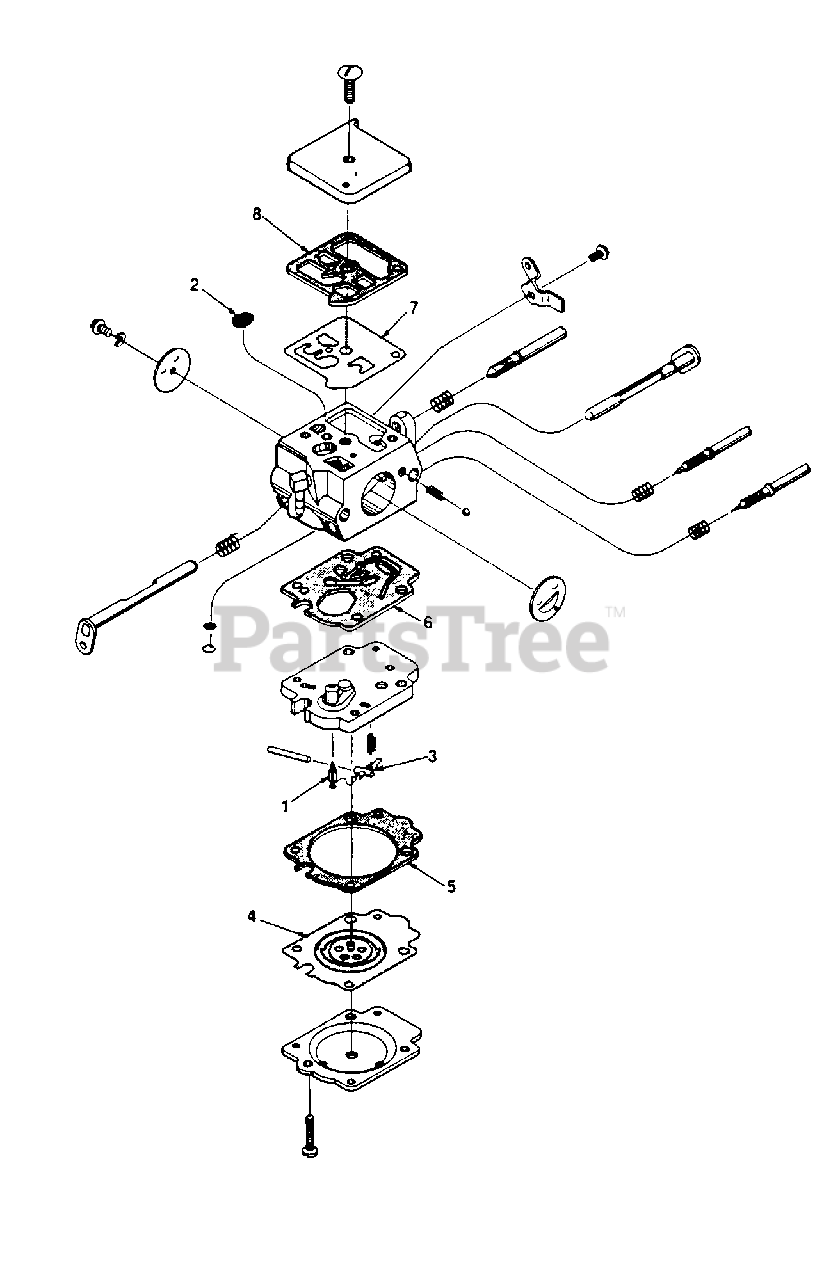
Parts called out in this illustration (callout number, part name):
1	Repair Kit
2	Repair Kit
3	Repair Kit
4	Repair Kit
4	Gasket-Diaphragm Kit
5	Repair Kit
5	Gasket-Diaphragm Kit
6	Repair Kit
6	Gasket-Diaphragm Kit
7	Repair Kit
7	Gasket-Diaphragm Kit
8	Repair Kit
8	Gasket-Diaphragm Kit
